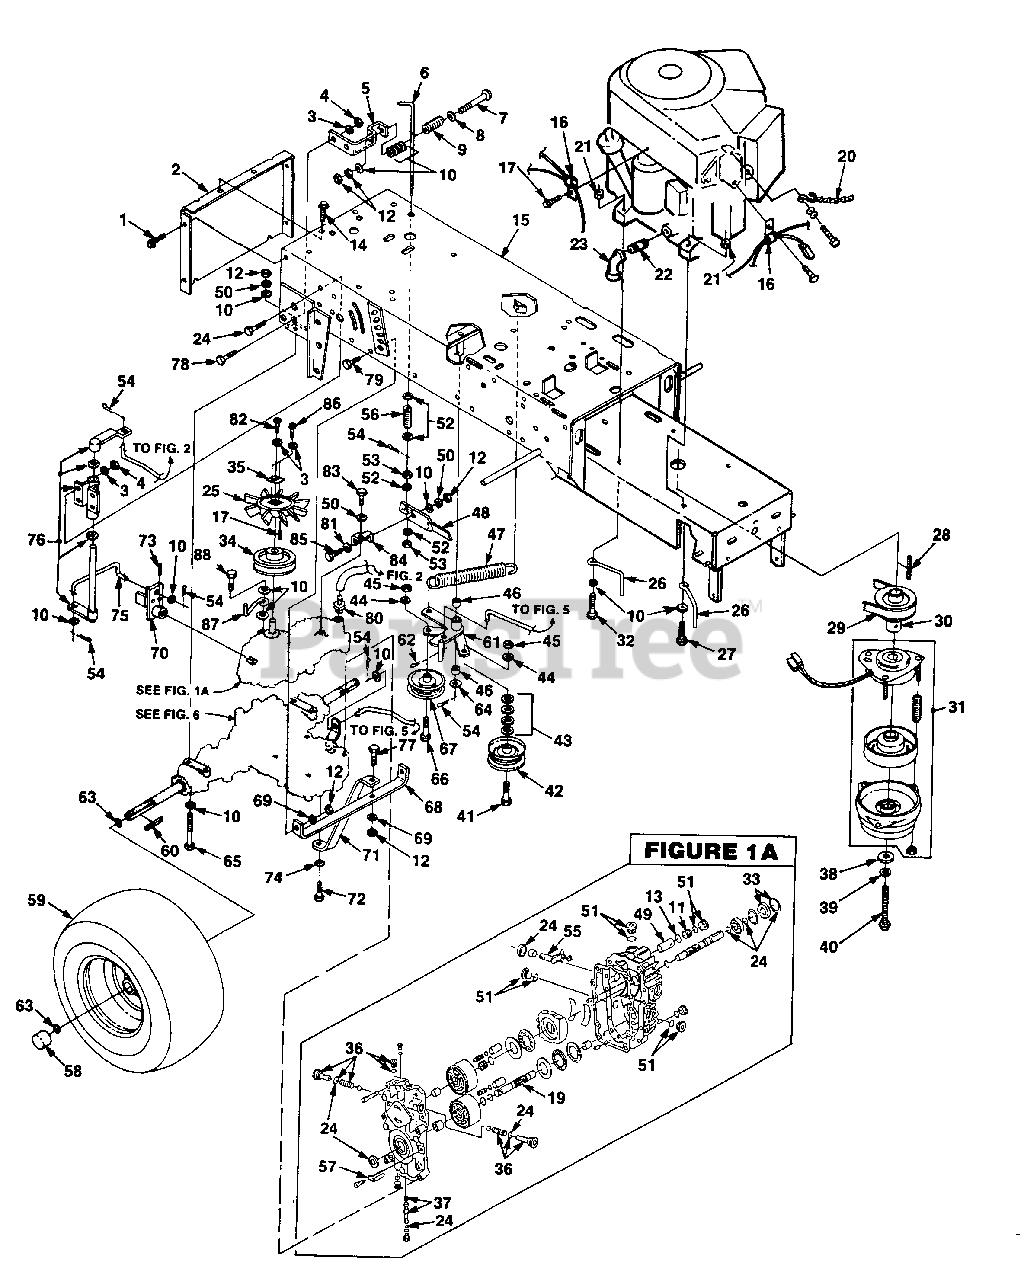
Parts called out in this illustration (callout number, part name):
1	SCREW- (1/4-14 x 1")
2	BRACKET- Hitch
3	WASHER- Lock (1/4")
4	NUT- Hex (1/4-20)
5	LIMITER- Bracket
7	BOLT- Rd. Hd. Sq. Neck (1/4-20 x 4 1/2")
8	WASHER (7/16")
9	SPRING- Compression
10	WASHER- Flat (5/16")
11	SPRING (Filter)
12	NUT- Hex (5/16-18)
13	WASHER (Filter)
14	SCREW- (1/4-20 x 9/16")
19	SHAFT- Motor
20	CHAIN- Restraining
21	NUT- Hex C'lock
22	NIPPLE- Pipe (3/8 x 2")
23	ELBOW- (3/8")
24	OVERHAUL- Seal kit
26	GUIDE- Front Belt
27	SCREW- (5/16-18 x 1 3/4")
29	BELT- Traction
30	PULLEY- Drive
31	CLUTCH- Brake
34	PULLEY- Drive
35	PLATE- Retainer
36	CHECK VALVE KIT
37	BYPASS VALVE KIT
38	CLUTCH- Retainer
39	WASHER- Lock (7/16")
40	SCREW- (7/16-20 x 3)
41	SCREW- (3/8-16 x 2)
42	IDLER- Inside
43	WASHER- Flat (3/8")
44	WASHER- Lock (3/8")
45	NUT- Hex (3/8-16)
47	SPRING- Extension
48	LINK- Dump
50	WASHER- Lock (5/16")
52	WASHER- Flat (1/4")
53	NUT- Lock (1/4-20)
54	PIN- Cotter (3/32-3/4")
55	UNION ARM
57	NAME PLATE
58	CAP- Rear Hub
59	REAR WHEEL ASSY.
60	KEY- (1/4 x 2.50)
61	BEARING ASSY.
63	RING- Snap
64	WASHER- Flat (1/2")
65	SCREW- (5/16 x 3")
66	SCREW- (3/8-16 x 1 3/4")
68	REINFORCEMENT
69	WASHER- Lock (5/16")
70	ARM & LUG
71	BRACKET- Rotation Control
72	SCREW- (5/16-18 x .88)
73	SCREW- Set (1/4-20 x 1/2")
74	WASHER- Flat (5/16")
76	PIVOT- Bracket & Arm
77	HEX BOLT- (5/16-18 x 1")
78	SCREW- (1/4-20 x 3/4")
79	SCREW- (5/16-18 x 3/4")
80	CONNECTOR
82	SCREW- (m6 x 1 x 12mm)
83	SCREW- (m8 x 1.25 x 50mm)
84	BRACKET- Pivot
85	SCREW- (5/16-18 x 7/8")
86	SCREW- (#10-24 x 5/8")
87	GUIDE BELT
88	SCREW- (m8 x 1 1/4 x 120mm)
